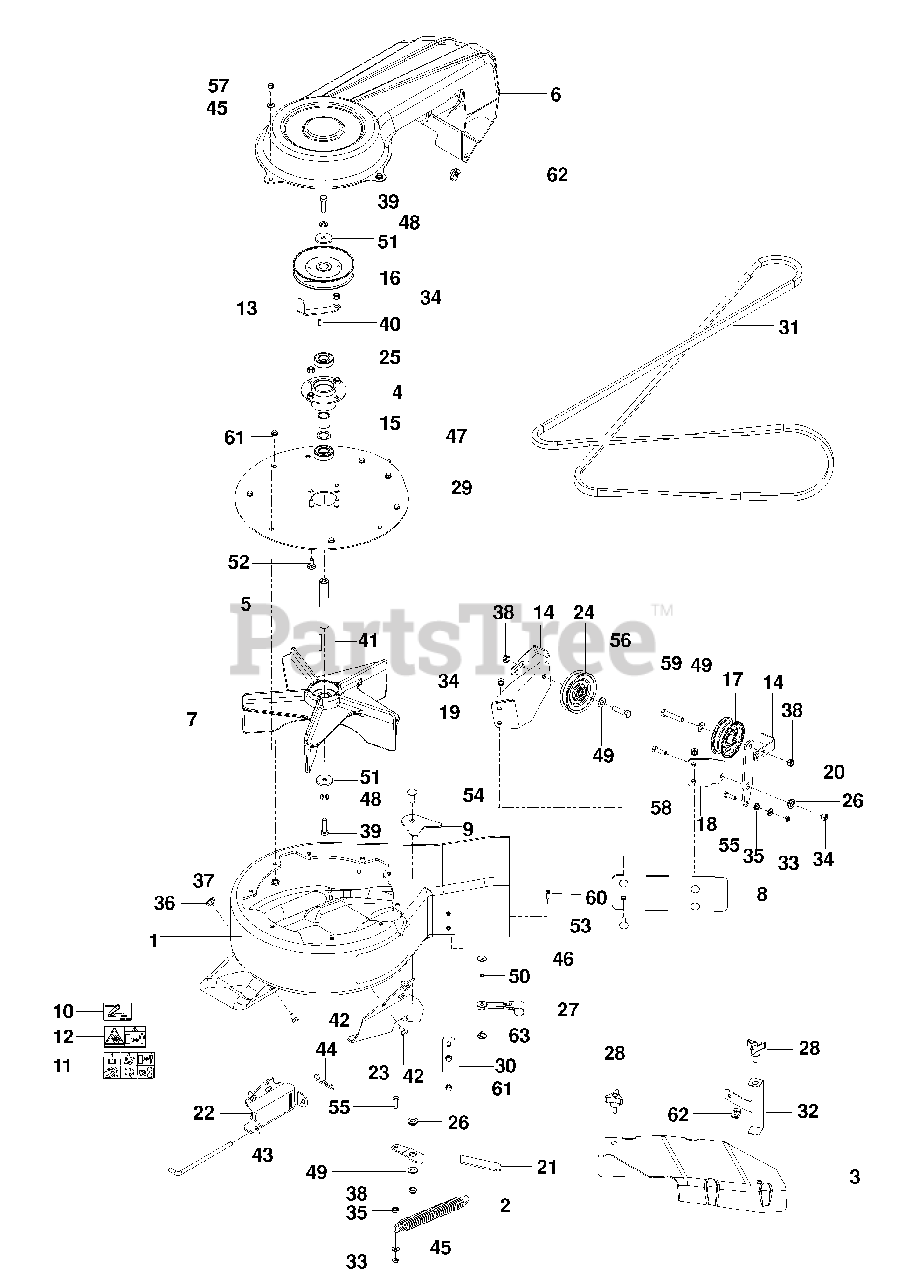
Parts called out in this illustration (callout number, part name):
1	HOUSING W/DECALS
2	TRACTION SPRING
3	COVER, BELT
4	HUB, BEARING
5	SHAFT, IMPELLER
6	COVER, BELT
8	PLATE, BACKING
9	PLATE, BACKING
10	DECAL, BELT ROUTING
11	DECAL, WARNING
12	DECAL, SEVERING
13	KEEPER, BELT, OUTER
14	KEEPER, BELT, REAR
17	PULLEY, IDLER
18	MOUNT, IDLER, UPPER
19	MOUNT, IDLER, LOWER
20	ARM, IDLER
21	ARM, TENSION
22	BRACKET, MOUNT, FRONT
23	BRACKET, MOUNT, REAR
27	LATCH, HOOD
28	KNOB w/ STUD
29	PLATE, OUTER
32	BRACKET, BELT COVER
33	NUT 1/4-20 HEX NYLOC
34	NUT 5/16-18 HEX NYLOC
35	NUT 1/4-20 HEX FLANGE
36	NUT 5/16-18 TEE
37	NUT 1/4-20 TEE
38	NUT 3/8-16 HEX JAM NYLOC
39	BOLT, HEX 3/8-24 x 1 1/4 GR 8
40	KEY 3/16 x 1/2
41	KEY 3/16 x 1 1/2
42	HCS 5/16-18 x 1/2
44	HAIRPIN COTTER
45	WASHER 1/4 FLAT SAE
46	WASHER, 3/16 x 3/4 x 16 GA
48	WASHER 3/8 SPLT LOCK
49	WASHER 3/8 SAE FLT
50	WASHER 3/16 LOCK
51	WASHER, HARDENED
52	RHSNB 5/16-18 x 3/4
53	RHSNB 5/16-18 x 1
54	RHSNB 3/8-16 x 1
55	HCS 1/4-20 x 7/8
56	HCS 3/8-16 x 1 1/2
57	HCS 1/4-20 x 1/2
58	HCS 5/16-18 x 1
59	HCS 3/8-16 x 1 3/4
60	SCREW 10-24 x .625 RD
61	SCREW 1/4 x 3/8 THRD FRM
62	RETAINER, U TYPE
63	WELD NUT, PLATED
